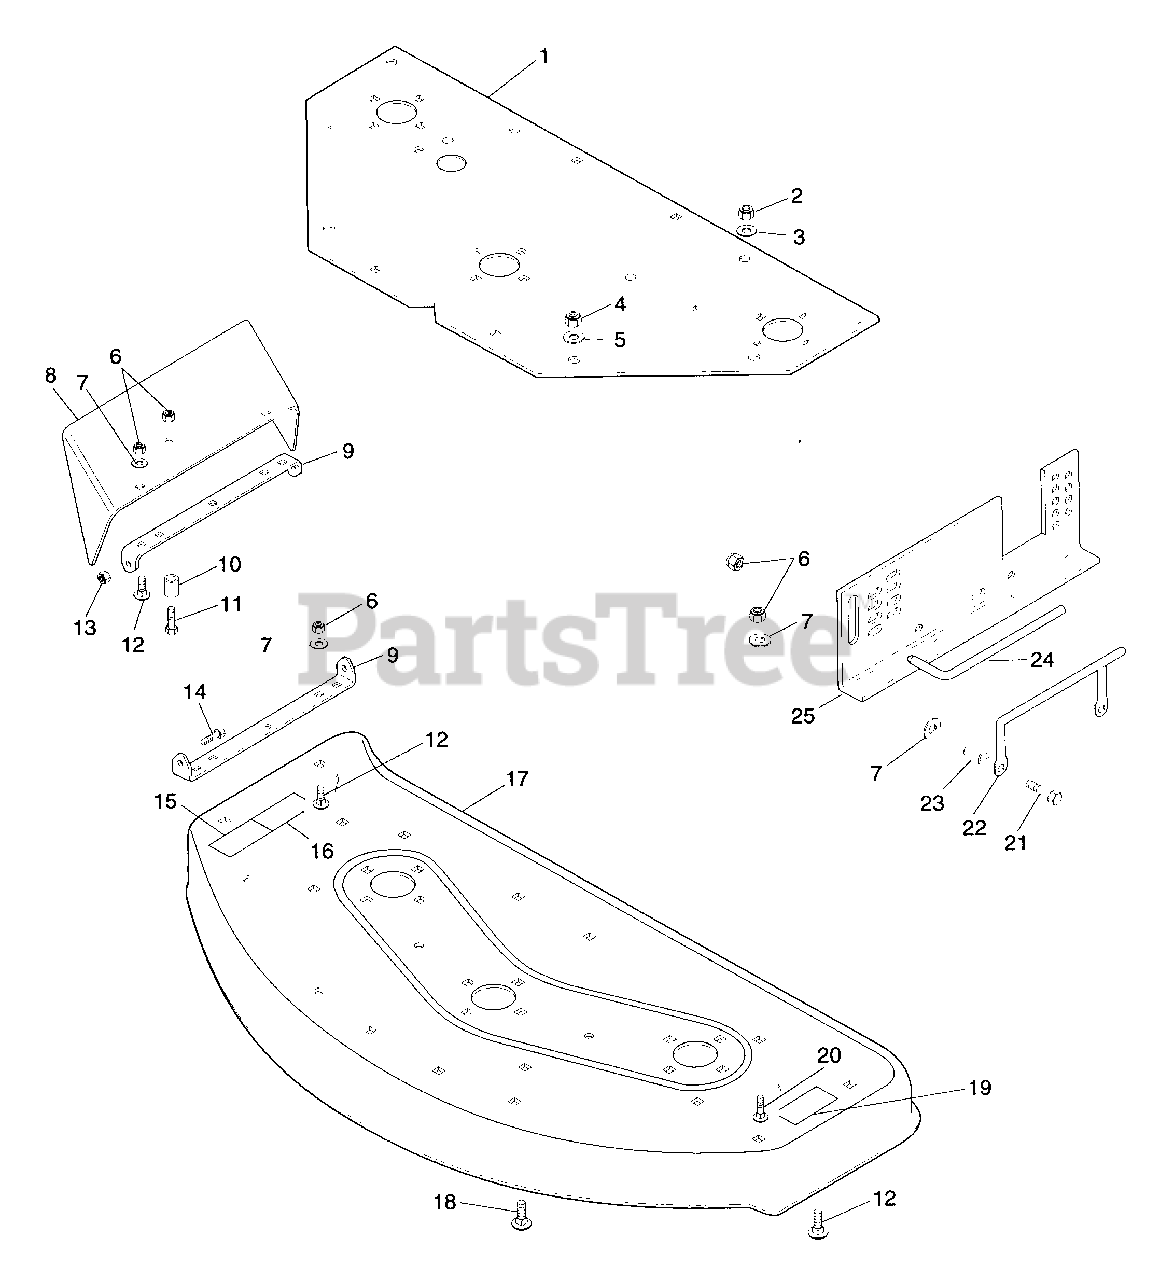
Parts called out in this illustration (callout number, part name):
1	Plt, Support
2	Nut-Lk-Nyl .312-18 Pl
3	Wshr-Fl-Stl .328 x 1.0 x .094 Pl
4	Nut-Lk-Nyl .50-13 Pl
5	Wshr-Fl-Stl .531 x 1.250 x .100
6	Nut-Lk-Nyl .375-16 Pl
7	Wshr-Fl-Stl .406 x .812 x .065
8	Chute, 40" Flip-Up
9	Brkt, Chute 40" Mower
10	Bshg-Slv .407 x .625 x .750 Pl
11	Blt-Hex .28-16 x 1.50 91 Gr 5
12	Blt-Rdhdsqnk .38-16 x 1.0 Pl
13	Nut-Lk-Nyl .250-20 Pl
14	Blt-Hex .25-20 x .875
15	Decal, Warning Eye
16	Decal, Danger Hand
17	Wldm't, 40" Deck 3-Spndl
18	Blt-Rdhdsqnk 50-13 x 1.00
19	Decal, Danger Foot
20	Blt-5/16-18 x Rdhdsqnk .75
21	Blt-Hex .38-16 x 1.75 Pl Gr 5
22	Handle
23	Bushing
24	Pin, Mower Locking
25	Brkt, Mwr Side Support (L.H.)
